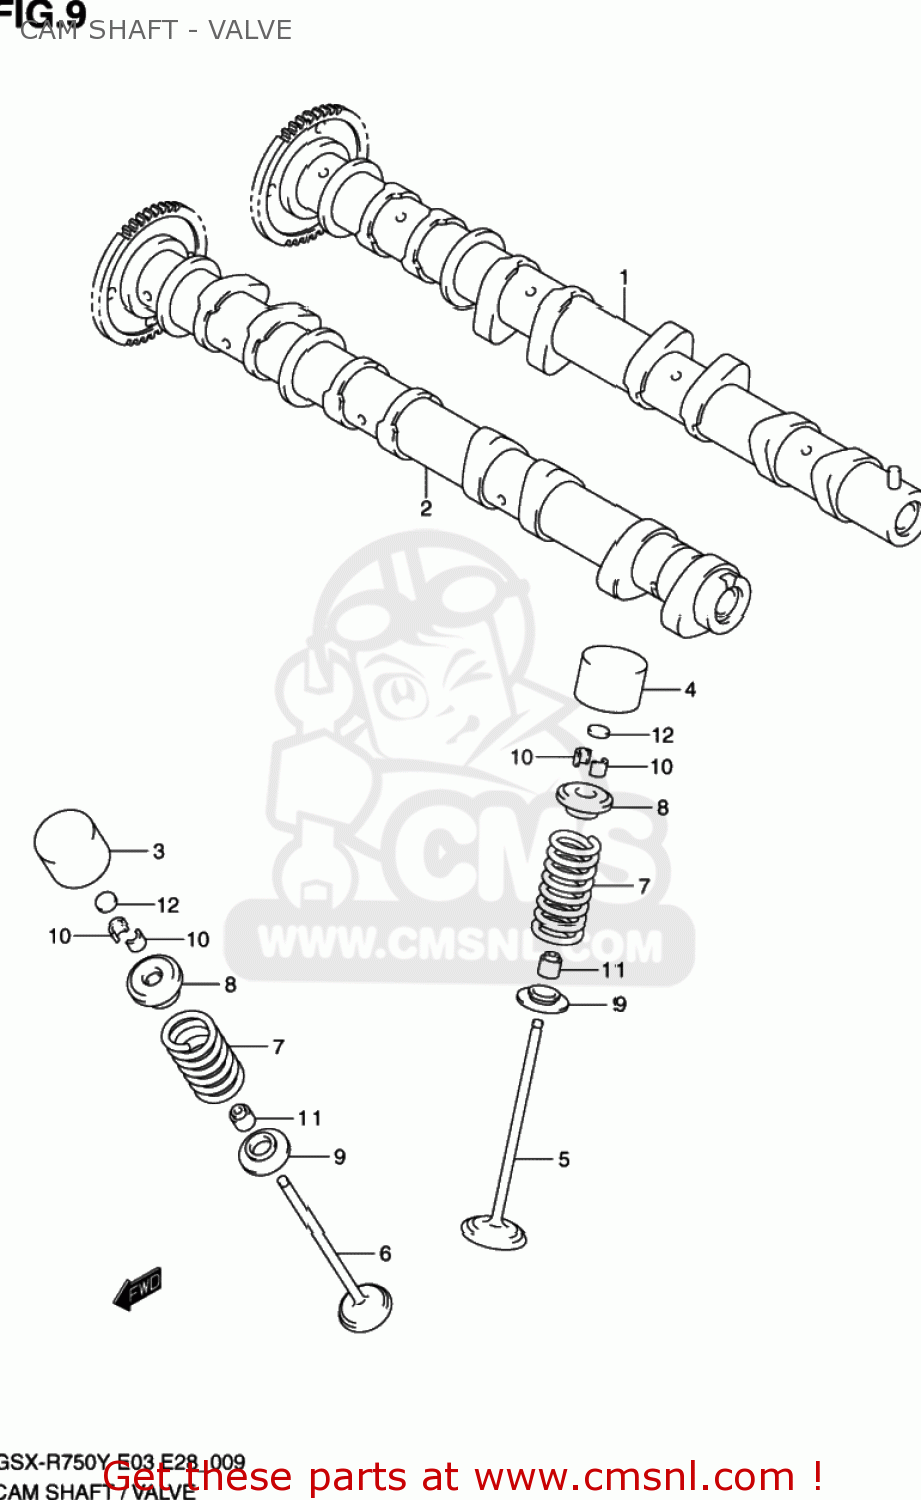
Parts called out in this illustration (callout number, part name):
1	CAMSHAFT,INTAKE
2	CAMSHAFT COMP,EXHAUST
3	TAPPET,EXHAUST
4	TAPPET
5	VALVE,INTAKE
6	VALVE,EXHAUST
7	SPRING,VALVE
8	RETAINER,VALVE SPRING
9	SEAT,VALVE SPRING
10	COTTER VALVE
11	SEAL,OIL(3.2X8.6X9)
12	SHIM,TAPPET
13	SHIM SET,TAPPET
14	CASE,TAPPET SHIM
